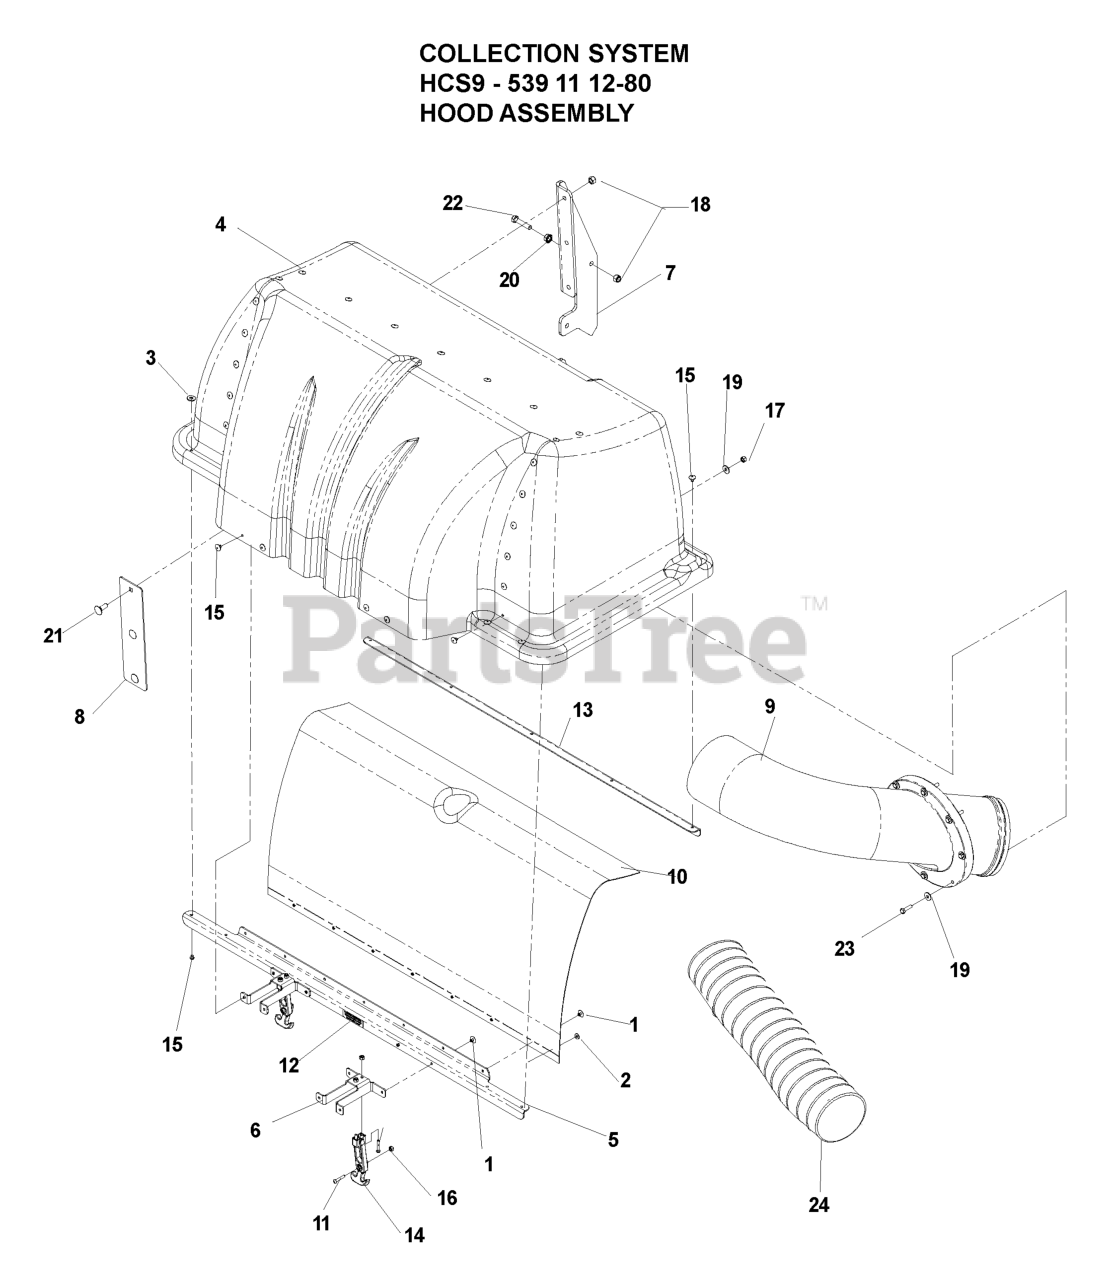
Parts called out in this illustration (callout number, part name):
1	RIVET E/16 X 1/4 LG FLG
2	WASHER #10
3	WASHER, #10 MACH SCR BLK OX
5	HOOD SUPPORT
6	SUPPORT, DRAW LATCH
7	HOOD HINGE
8	MOUNT PLATE
10	MESH, POLY DIAMOND
11	SCR, #10-24 X 1-1/8
12	DECAL, VENTILATION
13	HOOD SUPPORT, REAR
14	DRAW LATCH, FLEXIBLE T-HANDLE
15	RIVERT, 3/16, STAVEX
16	NUT 10-24 NYLOC
17	NUT.1/4-20.HEX.NYLOC.ZD
18	NUT 3/8-16 NYLOC
19	WASHER 1/4 FLAT
20	NUT 3/8C WHIZ
21	RHSNB 3/8C X 1
22	HCS 3/8-16 X 1 3/4 GR5
23	BOLT 1/4C X 1 3/4
24	HOSE 7 X 54 CLEAR
539111280	Hood Assembly Collection System (HSC9)
